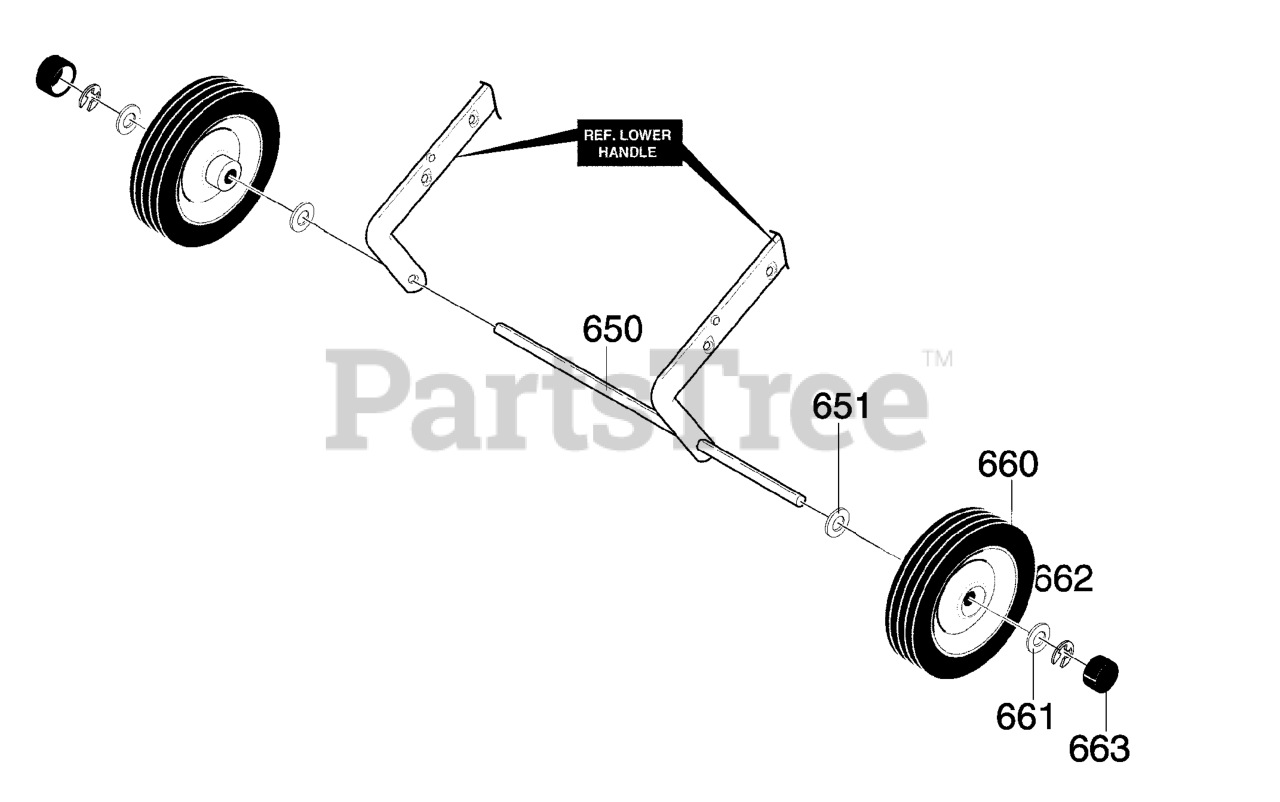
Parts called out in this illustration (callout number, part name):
650	AXLE, 7 x 1.5
651	FLATWASHER
660	TIRE & RIM
661	FLATWASHER
663	HUB CAP
